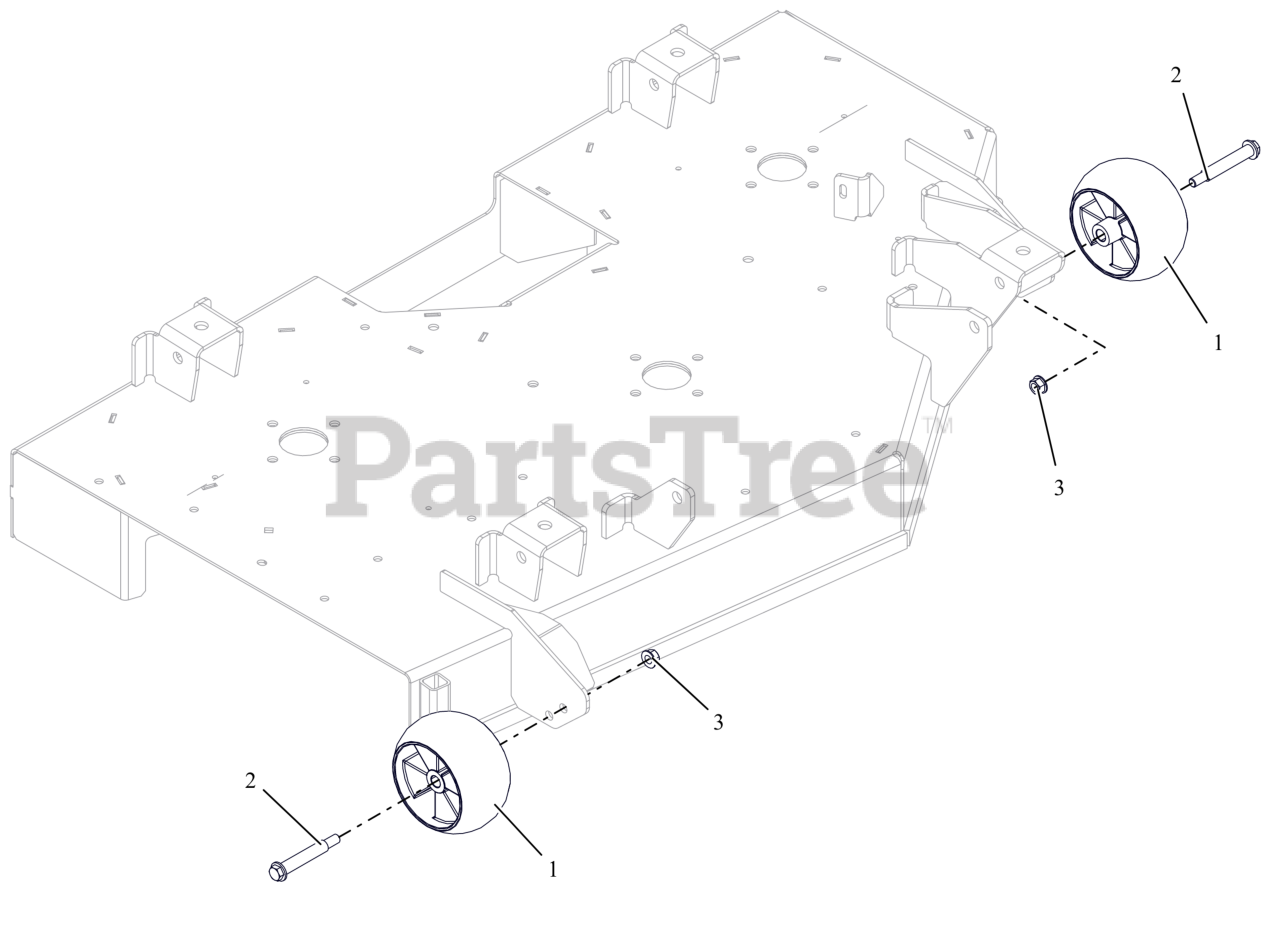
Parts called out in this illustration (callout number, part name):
1	ANTI-SCALP WHEEL - 5X OS
2	BLT-SHLDR .38-16X2.50 HWH G5
3	NUT-LK-CTR-FLG .375-16 GF ZCC
